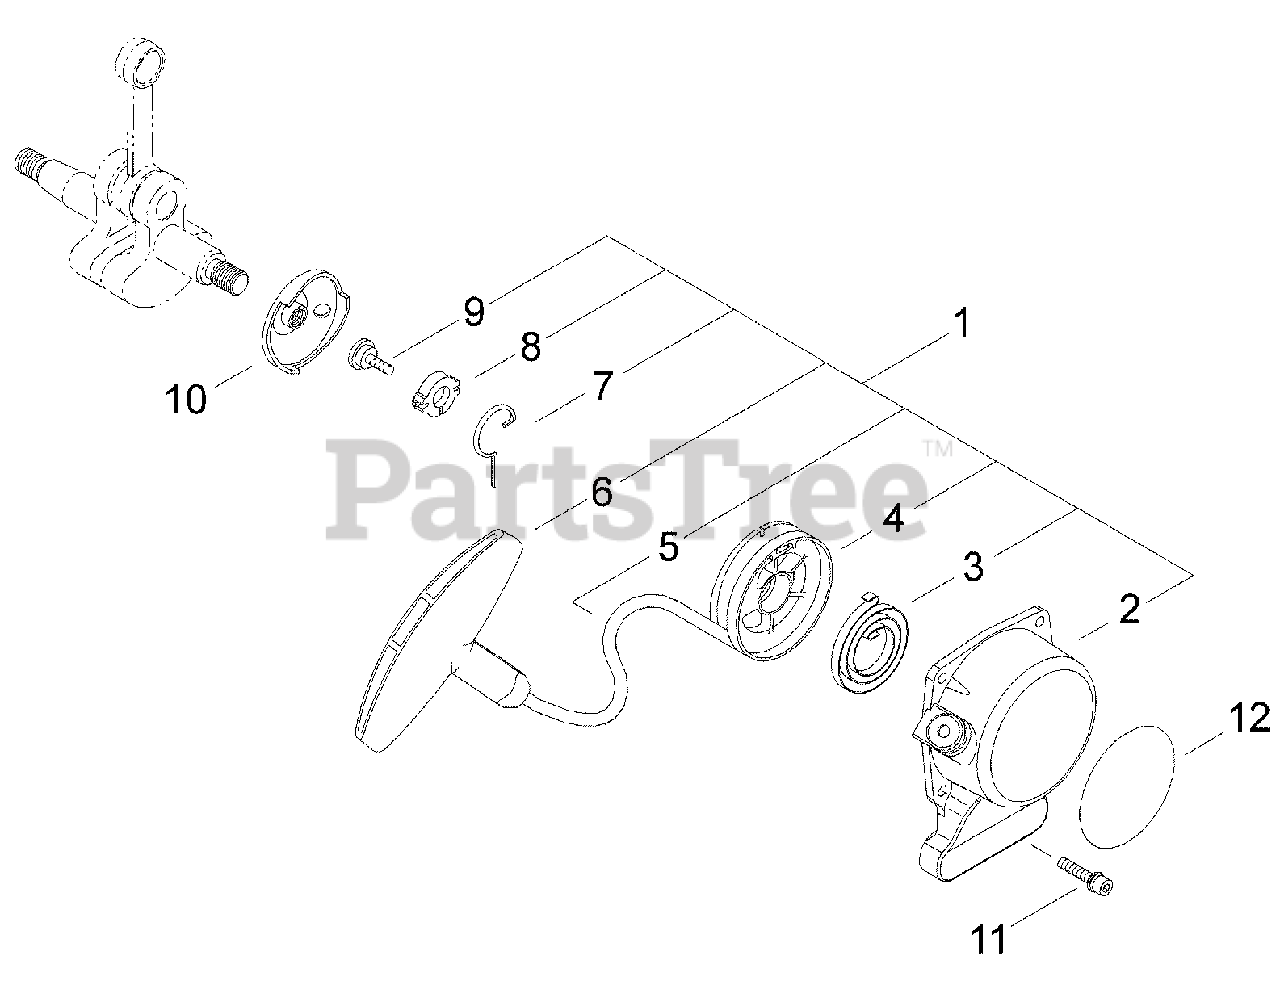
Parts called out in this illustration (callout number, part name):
1	STARTER ASSY, RECOIL
2	CASE, RECOIL STARTER
3	SPRING, RECOIL
4	REEL, ROPE
5	ROPE, STARTER
6	GRIP, STARTER
7	ARM, SWING
8	WASHER 5
9	SCREW 5
10	PULLEY, STARTER
11	BOLT M4×14
12	LABEL, SWISHER E4
